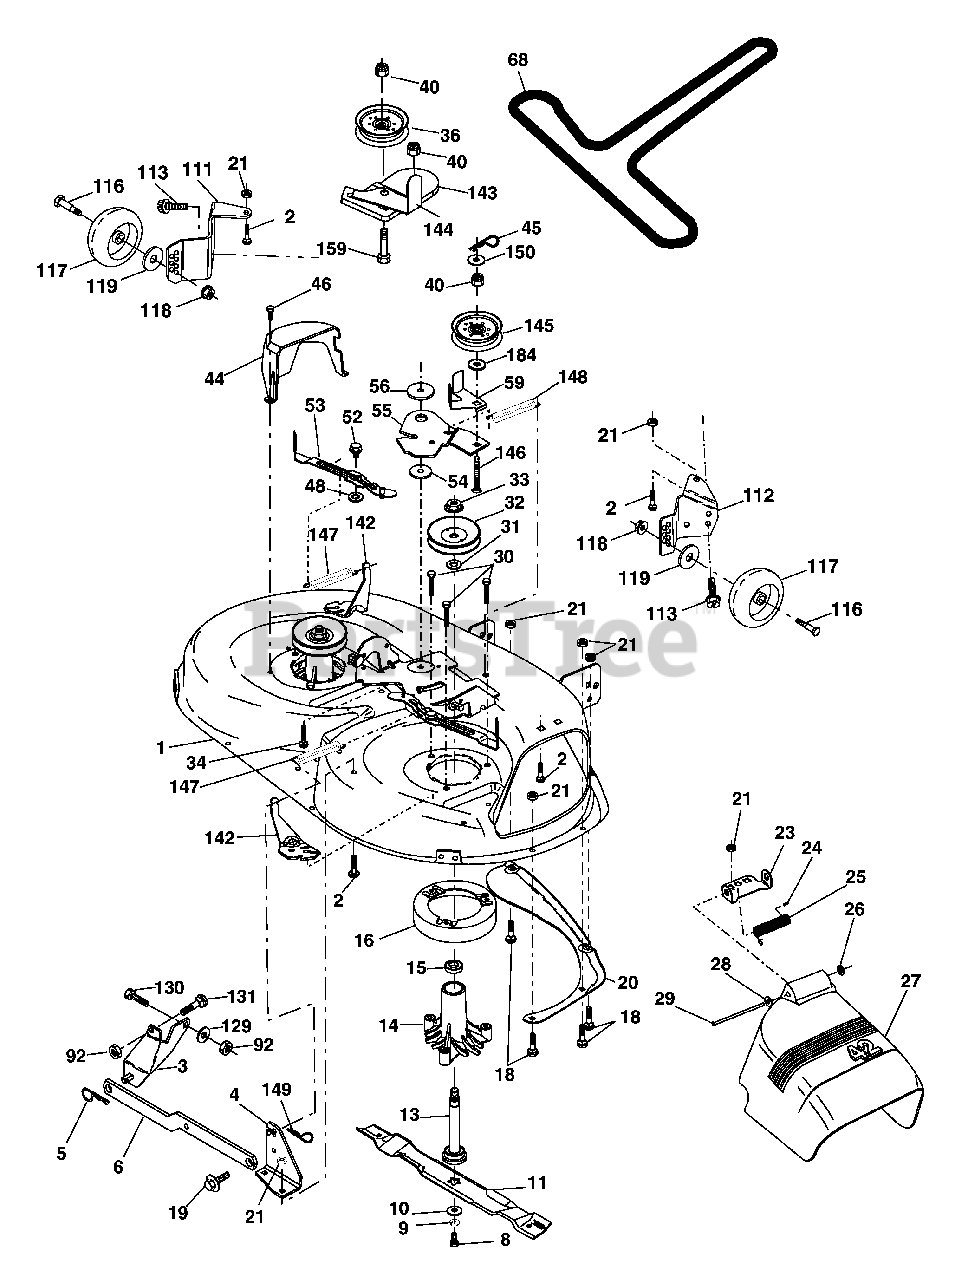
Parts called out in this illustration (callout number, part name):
1	Mower Deck Assembly, 42"
2	Bolt
3	Bracket Asm Fr. Sway Bar 3/42
4	Bracket Asm Deck 42" Sway Bar
5	Retainer Spring
6	Bar Sway Deck
8	Bolt 3/8-24 x 1.25 Gr. 8 patched
9	Washer, Lock
10	Washer, Hardened
11	Blade Mower 42" Hi-Lift
11	Blade, Mulching 42" Std
11	Blade Mulching 42" Premium
13	Shaft Assembly, Mandrel, Vented
14	Housing, Mandrel, Vented
15	Bearing, Ball, Mandrel
16	Stripper, Mandrel Deck
18	Bolt, Carriage 5/16-18 x 5/8
19	Bolt, Shoulder
20	Baffle, Vortex
21	Nut
23	Bracket, Deflector Mower 42"
24	Cap, Sleeve 80 x 112 Blk Mower
25	Spring, Torsion, Deflector 2 52
26	Nut, Push Phos & Oil
27	Shield, Deflector 42" Blk
28	Washer 11/32 x 5/8 x 16 Ga.
29	Rod, Hinge 42" 6 75 W/G
30	Screw Thdrol
31	Washer, Spacer Mower Vented
32	Pulley, Mandrel
33	Nut, Toplock
34	Bolt Carr SH 3/8-16 x 1-1/2 Gr.5
36	Pulley, Idler, Flat
40	Nut Lock 3/8-16
44	Guard, Mandrel, LH
45	Retainer
46	Screw, Thdrol 1/4-20 x 5/8 T
48	Washer Hardened
52	Bolt Shld 5/16-18
53	f Arm Asm Brake
54	Washer, Hardened
55	Arm, Idler
56	Spacer, Retainer
59	Guard TUV Idler
68	V-Belt, 42" Mower
92	Nut Lock W/Ins 3/8-16 UNC
111	Bracket Whl Ga. LH
112	Bracket Whl Ga. RH
113	Screw 5/16-18
116	Bolt, Shoulder
117	Wheel, Gauge
118	Nut Centerlock 3/8-16
119	Washer 3/8 x 7/8 x 14 Ga.
129	Washer 13/32 x 13/16 x 12 Ga.
130	Bolt Fin HEx 3/8-16 unc x 1 Gr. 5
131	Bolt RDHD SQNK 3/8-16 unc x 1
142	Arm Spring Brake Mower
143	Bracket Arm Idler 42"
144	Keeper Belt 42" Clutch Cable
145	Pulley Idler Flat
146	Bolt Carriage Idler
147	Spring Extention
148	Spring Return Idler
149	Retainer Spring Yellow
150	Washer 9/32 x 3/4 x 10 Ga.
159	Bolt Rdhd Sqn 3/8-16 unc x 1-3/4
184	Washer 13/32 x 7/8 x 10 Ga.
